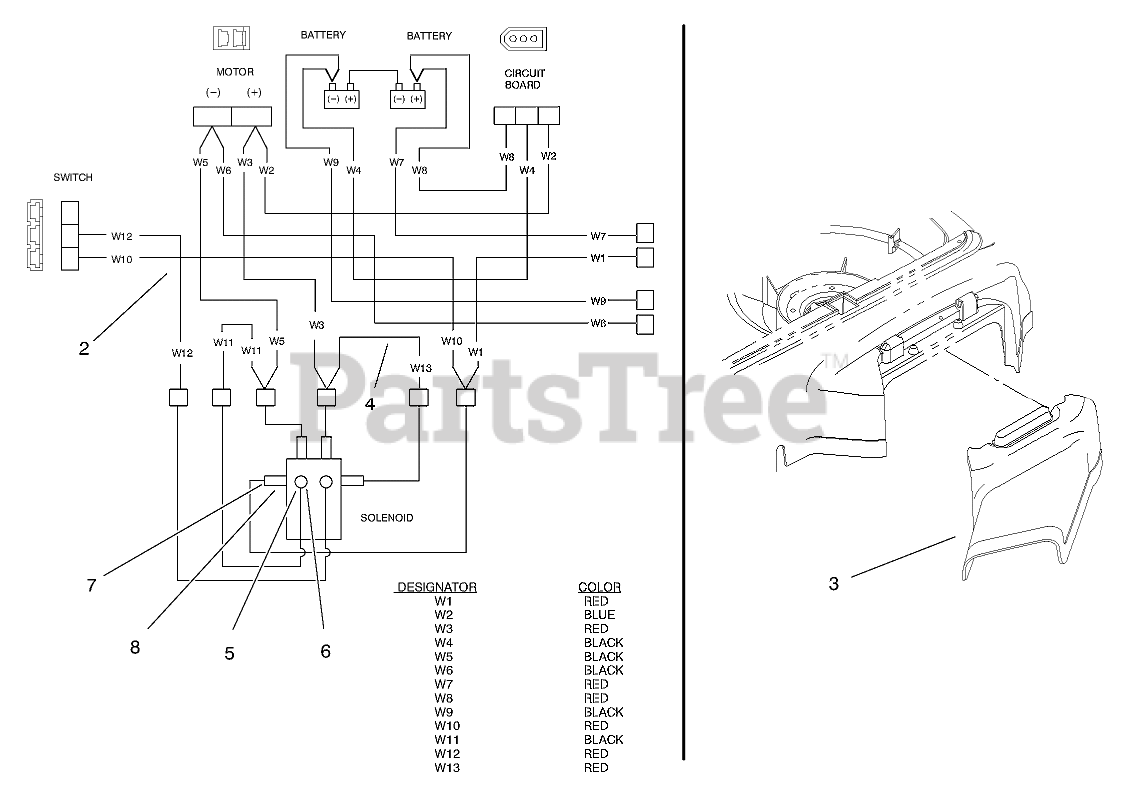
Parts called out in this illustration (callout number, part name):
2	Harness-Wire (Incl. W1-W12)
3	CHUTE - SIDE
4	Harness-Wire (Incl. W13)
5	NUT-HJ
6	WASHER-LOCK
7	NUT-JAM
8	WASHER-LOCK
